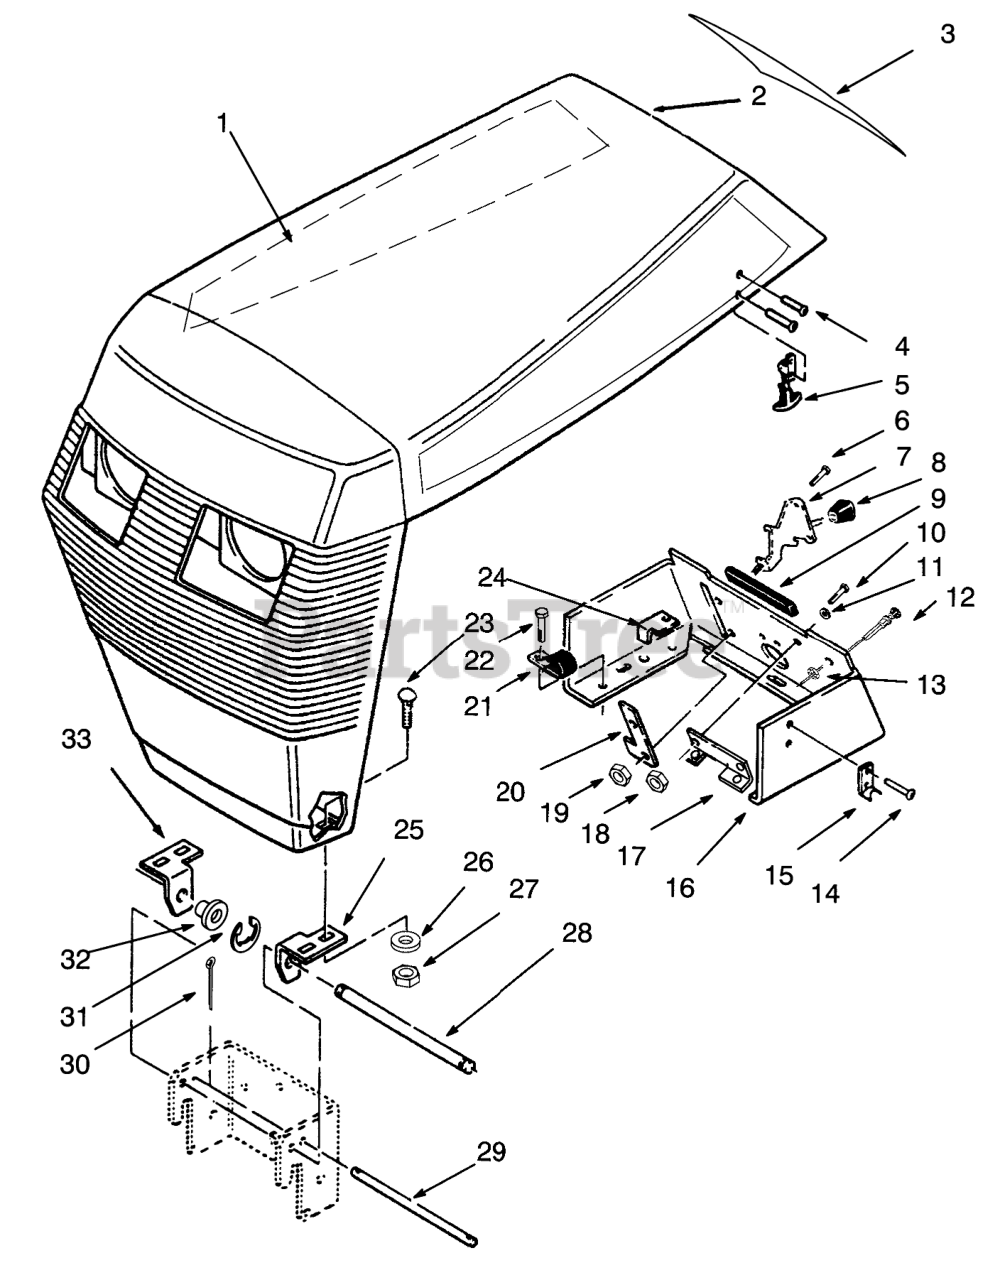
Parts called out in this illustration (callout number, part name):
1	DECAL-HOOD 416-8 R H
2	Hood (Incl. Ref. #3)
3	Decal-Danger
4	RIVET-POP
5	Handle Assembly (Incl. Ref. #15)
6	SCRW-PHC
7	CONTROL-THROTTLE
8	KNOB-CONTROL
9	EDGING-CONSOLE
10	SCREW-PAN
11	Washer-Lock
12	CONTROL-CHOKE
13	NUT-HEX PALNUT
14	POPRIVET 1/8X 1/8 BK
15	KEEPER-LATCH
16	Console
17	BRACKET
18	Nut
19	Nut
20	Washer
21	J-CLIP
22	Bolt
23	SCREW-CARR
24	STOP-PTO
25	BRACKET-GRILL, LH
26	WASHER-FLAT
27	NUT-LOCK
28	ROD-GRILL PIVOT
29	ROD-HOOD STOP
30	Pin-Cotter
31	RING-RETAINING
32	BUSHING-NYLINER
33	BRACKET-GRILL, R H
